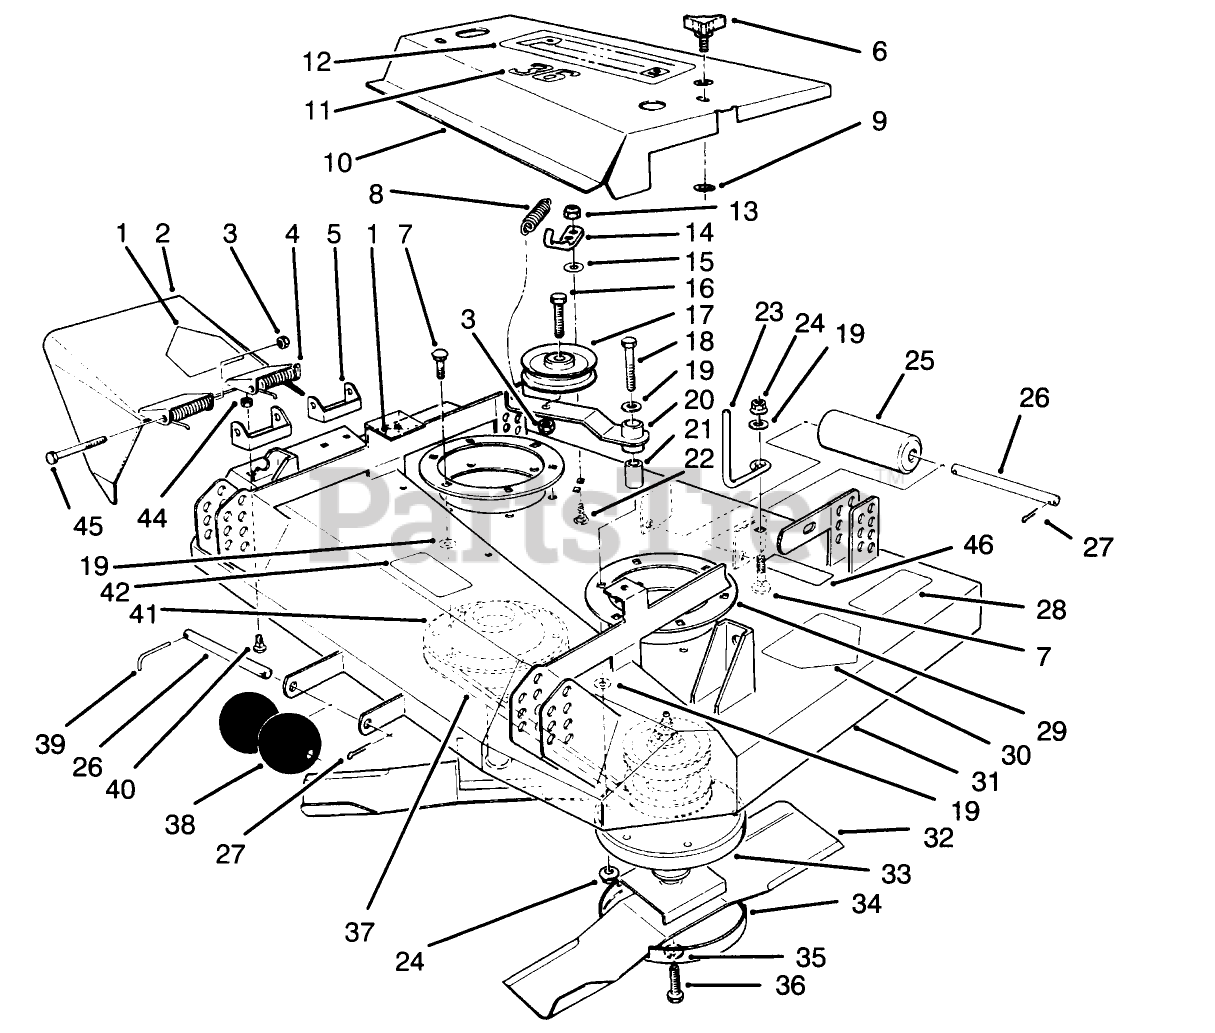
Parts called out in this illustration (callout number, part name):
1	DECAL-DANGER
2	Deflector-Grass (Incl. Ref. #1)
3	NUT-HEX
4	SPRING
5	Bracket-Pivot
7	SCREW-CARR
8	SPRING-EXTENSION
9	RING-RETAINING
10	Cover ASM
11	Decal-36 Inch
12	DECAL-PROLINE
13	NUT-LOCK, NI
14	ROD - SPRING
15	WASHER-FLAT
16	SCREW-HH
17	PULLEY-IDLER
18	SCREW-HH
19	WASHER-FLAT
20	Wa-Arm
21	SLEEVE-PIVOT, IDLER
22	SCREW-CARR
23	ROD-BELT
24	NUT-HF
25	ROLLER-DECK
26	SHAFT-ROLLER
27	PIN-COTTER
28	DECAL-TORQUE
29	SUPPORT-DECK, RING
30	DECAL-DANGER
31	Deck Assembly (Incl. Ref. #28, 30, 42 & 46)
32	BLADE-SAIL, EXTRA HIGH
33	HOUSING - SPINDLE ASM
34	CUP-SCALP, ANTI
35	WASHER-LOCK
36	SCREW-BLADE
38	ROLLER
39	PIN-SPECIAL
40	SCREW-CARR
41	SPINDLE ASM
42	DECAL-DANGER, THROWN OBJECT
44	NUT-LOCK, CONE
45	SCREW-HH
46	DECAL-DANGER
